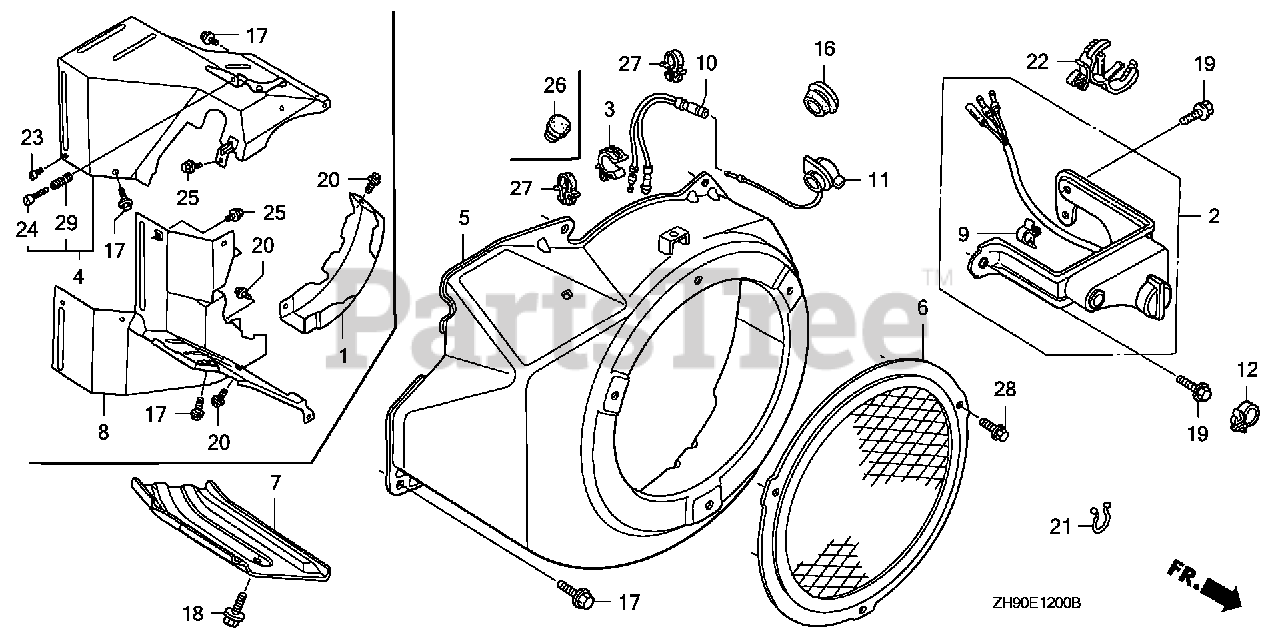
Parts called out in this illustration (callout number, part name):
2	ALERT UNIT, OIL SWITCH ENGINE STOP
3	CLIP, TUBE
5	COVER, FAN *NH105* (MAT BLACK)
5	COVER, FAN *R280* (POWER RED)
9	CLIP, IGNITION WIRE (8MM)
10	SUB-HARNESS
11	SWITCH ASSY., ENGINE STOP
16	GROMMET, DRAIN HOLE
17	BOLT, FLANGE (6X12) (CT200)
18	BOLT, FLANGE (6X12) (CT200)
19	BOLT, FLANGE (6X12) (CT200)
22	CLIP, HARNESS
